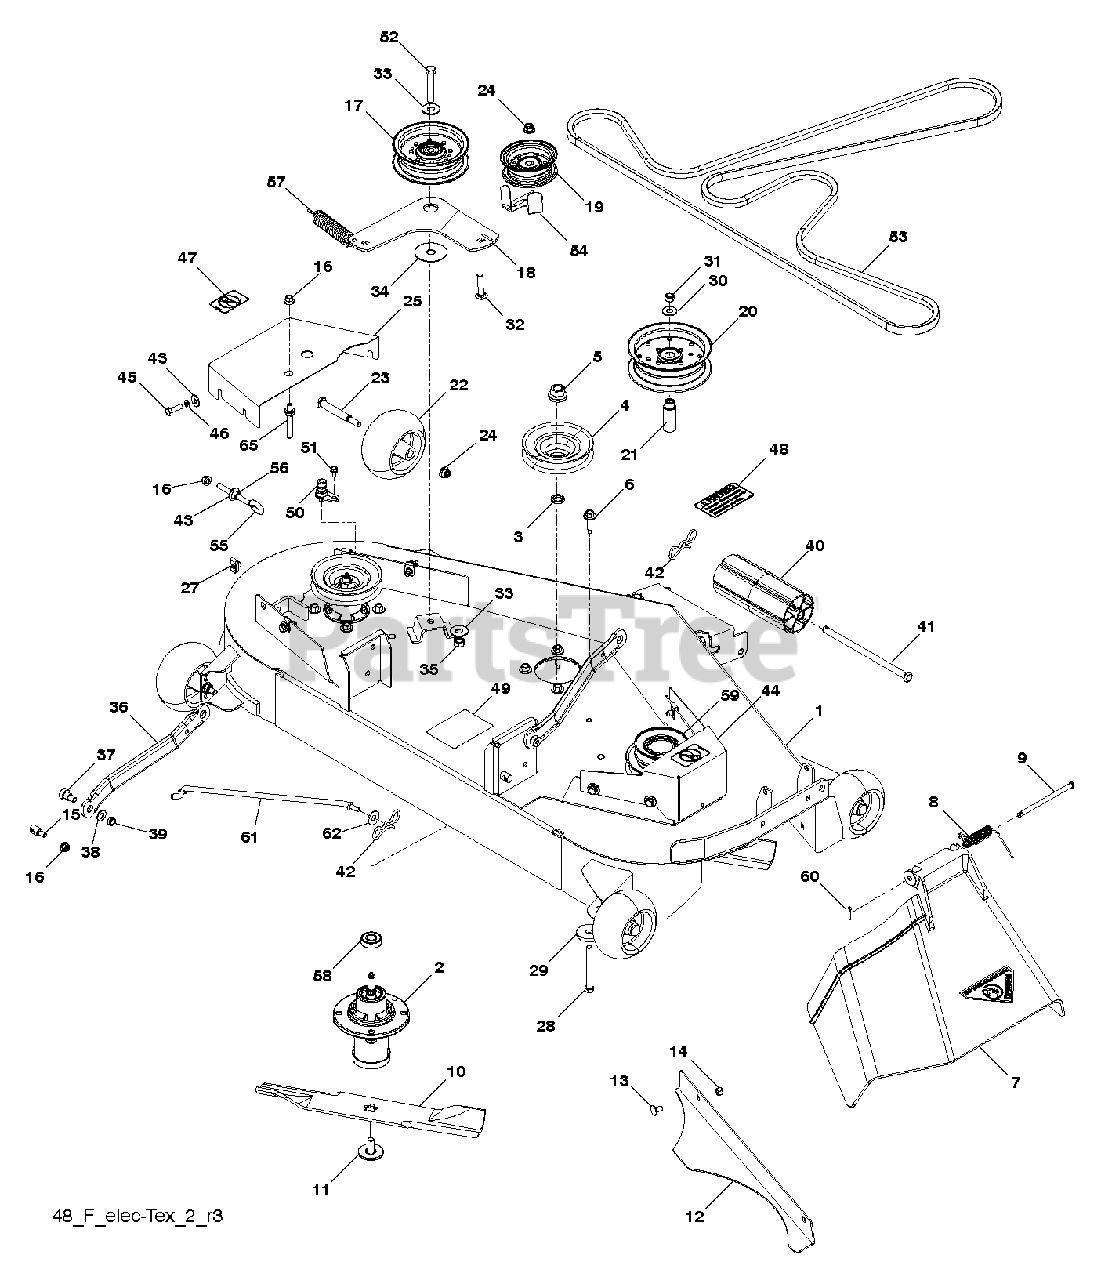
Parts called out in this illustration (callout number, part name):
1	DECK RAW WLDT 48"
2	MANDREL.DECK.ASSEMBLY
3	WASHER.SPACER.MANDREL
4	PULLEY.DRIVEN.DECK.48'
5	NUT.FLANGE.LOCK.TOP
6	SCREW, WASHER HEAD
7	DISCHARGE CHUTE 48"
8	SPRING - TORSION
9	PIN, CLEVIS 5/16 X 5.19
10	BLADE, 16-1/4"
11	BOLT.WASHER.ASM.7/16-2
12	CONFINEMENT PLATE 48" BLK
13	BOLT
14	NUT.71038.31-18.HEX.NYLOCK
15	STUD.FASTNER.W/ANTI-ROTATE
16	5/16-18 NYLOC FLANGE NUT
17	PULLEY.IDLER.MWR.STATI.LH
18	ARM IDLER RAW
19	PULLEY.IDLER.FLAT
20	PULLEY, IDLER
21	BUSHING, IDLER
22	GAUGE WHEEL
23	BOLT.SHOULDER.3/8-16X3-5/8.
24	NUT 3/8-16 HEX FLG NYLOC ZD
27	U-CLIP 5/16-18 NUT RETAINER
28	HCS 3/8-16 X 3-1/2 GR5 ZD
29	SPINDLE WASHER
30	WASHER 3/8 FLAT
31	NUT 3/8-16 NYLOC
32	RHSNB 3/8-16X1-3/4
33	WASHER 7/16 FLAT ZD
35	NUT.LOCK.FLANGE.7/16
36	ARM.SUSPENSION.MOWER
37	SB 3/8-16 X 3/8 SKT HD ZD
38	WASHER
39	NUT HEX 3/8-16 NYLON, THIN
40	NOSE ROLLER 48"
41	ROD.ROLLER.NOSE.NARROW.48"
42	PIN.COTTER.5/16.BOW TI
43	WASHER
45	BOLT.FIN.HEX.5/16-18UNC X 1.00
46	WASH.5/16.SLW.ZD
47	DECAL, NO STEP
48	DECAL, CAUTION
49	DECAL.MOWER.SCH.48/54
50	PORT.WASHOUT
51	SCREW
52	BOLT.HEX.7/16-14
53	BELT, 135" EL
54	GUARD, BELT
55	EYE BOLT 5/16 X 3.50
56	NUT.LOCK.FLANGE.7/16
58	BEARING, BALL
59	RP PULLEY, COLLECTION 48
60	RETAINER CLIP
61	ROD.ANTI.SWAY.48/54"K4
62	WASHER
63	PIN.COTTER.5/16.BOW TI
65	KEEPER.BELT.ENGINE
